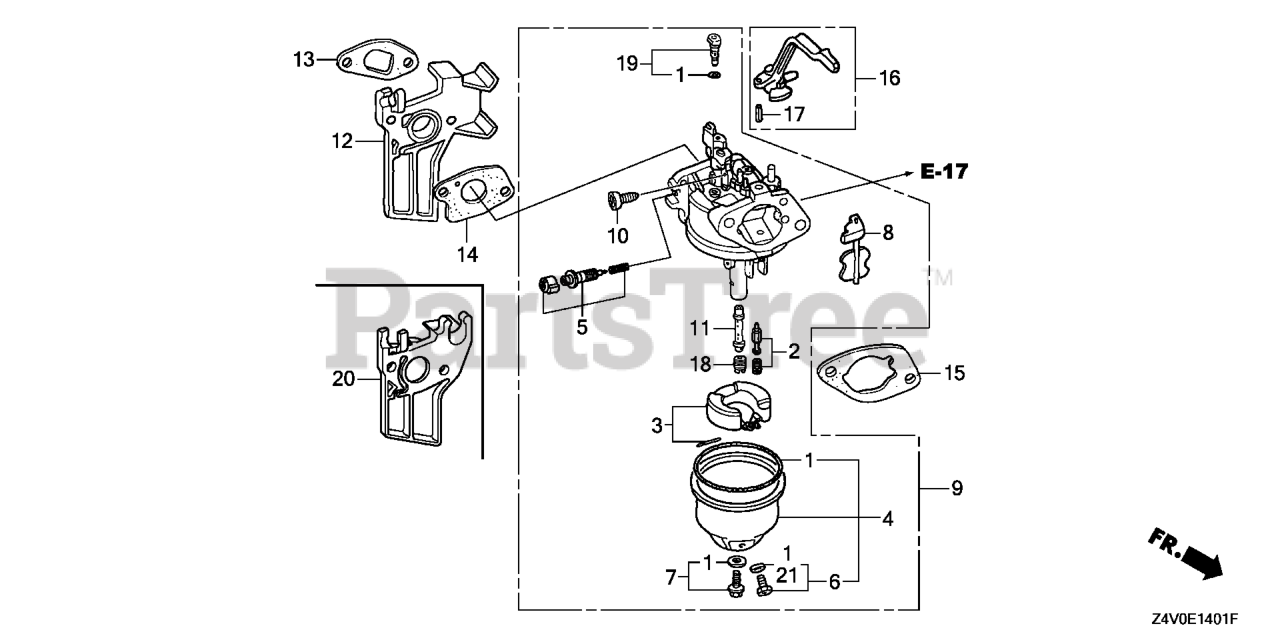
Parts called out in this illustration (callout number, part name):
1	GASKET SET (CARBURETOR NO.)
2	VALVE SET, FLOAT (CARBURETOR NO.) (SEAT NOT INCLUDED)
3	FLOAT SET
4	CHAMBER SET, FLOAT
5	SCREW SET (CARBURETOR NO.)
6	SCREW SET, DRAIN
7	SCREW SET (CARBURETOR NO.)
9	CARBURETOR ASSY. (BEA0N A)
10	SCREW, THROTTLE STOP
11	NOZZLE, MAIN (CARBURETOR NO.)
13	GASKET, INSULATOR
14	GASKET, CARBURETOR
15	GASKET, AIR CLEANER
16	LEVER, CHOKE
17	PIN, SPRING (2X12)
18	JET, MAIN (#78) (CARBURETOR NO.)
18	JET, MAIN (#80)
18	JET, MAIN (#82)
19	JET SET, PILOT (#38)
20	INSULATOR, CARBURETOR
21	WASHER, PLAIN (6.2X10.7 DRAIN) (CARBURETOR NO.)
